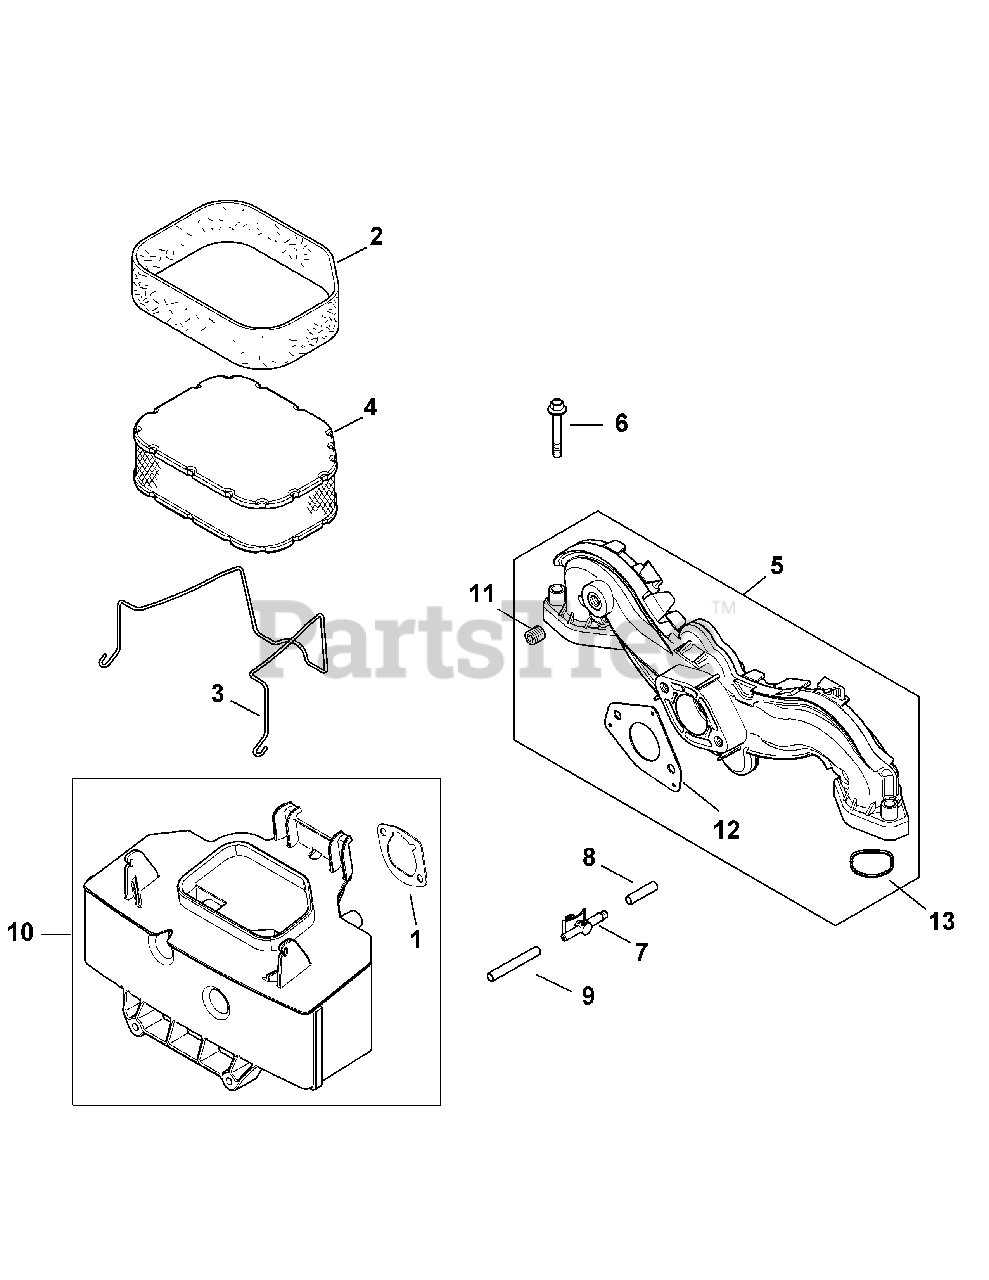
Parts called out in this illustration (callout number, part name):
1	Air Cleaner Base Gasket
2	Pre-Cleaner Element
3	Air Cleaner Element Latch
4	Air Filter & Pre-Cleaner Elements
5	Intake Manifold Kit
6	Flange Screw, M6 x 1.0 x 40
7	Evaporative Connector
8	Evaporative Mask
9	Evaporative Hose, 20"
10	Air Cleaner Base
11	Pipe Plug, 1/8
12	Carburetor Gasket
13	Intake Port O-Ring
